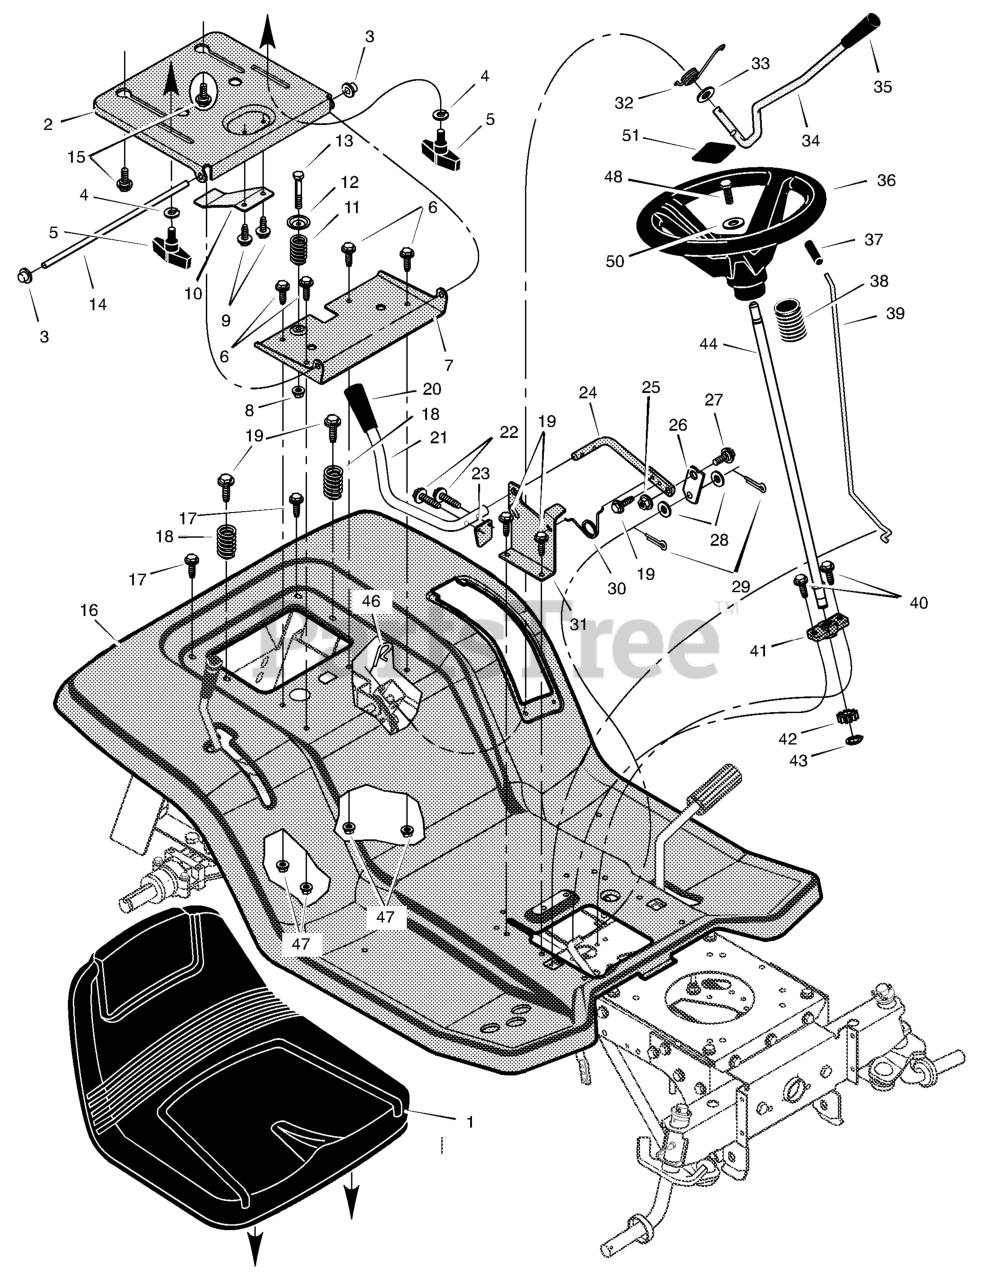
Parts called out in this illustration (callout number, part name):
2	Support, Seat
3	Push-On Cap
4	Washer
5	Bolt, Wing
6	Bolt
7	Bracket, Pivot
8	Nut
10	Spring, Leaf
11	Spring
12	Washer, Cup
14	Rod, Pivot
15	Bolt, Shoulder
16	Deck, Seat
20	Grip
21	Handle, PTO
22	Screw, Hex
23	Paddle, Switch
24	Lever, PTO
25	Nut
26	Link, PTO
27	Shoulder, Bolt
29	Pin, Cotter
31	Bracket, PTO
34	Handle, Lift
35	Grip
36	Wheel, Steering
38	Bellows
39	Rod, Parking Brake
41	Bearing, Lower
42	Gear, Pinion
44	Shaft, Steering
46	Pin, Cotter
47	Nut
48	Screw, Hex
50	Washer
51	Insert, Steering Wheel
